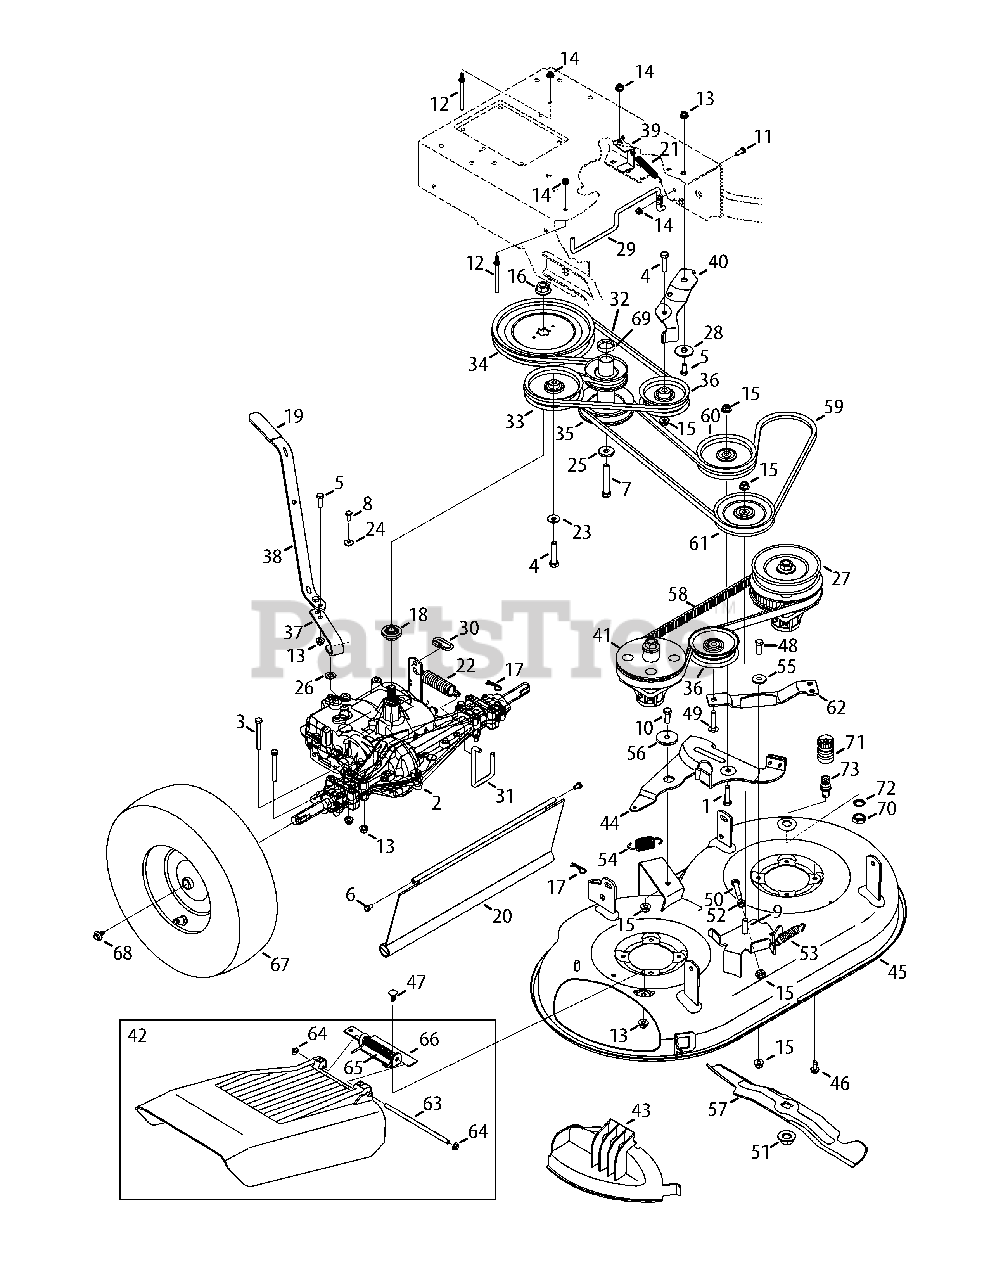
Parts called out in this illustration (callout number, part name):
1	Hex Head Cap Screw, 3/8-16 x 1.75
2	4 Speed Drive Assembly, Tecumseh
3	Hex Head Cap Screw, 5/16-18 x 2.75
4	Hex Head Cap Screw, 3/8-16 x 1.75
5	Hex Head Cap Screw, 5/16-18 x 1.00
6	Screw, 10-16 x 0.625
7	HHCS, 7/16-20 x 2.75
8	Hex Head Cap Screw, 1/4-28 x .625
9	Hex Head Cap Screw, 3/8-16 x 1.50
10	Hex Head Cap Screw, 3/8-16 x 1.25
11	Hex Head Cap Screw, 1/4-20 x .75
12	Belt Keeper, .25 DIA X 3.0
13	Flangelock Nut, 5/16-18
14	Flangelock Nut, 1/4-20
15	Flangelock Nut, 3/8-16
16	Flange Nut, 9/16-18
17	Click Pin, .092 x 1.64 LG
18	Spline Pulley Hub, 5/8
20	Trailshield, 8.35 x 19.17
21	Extension Spring, Wheel Drive
22	Extension Spring, Brake
23	Washer, Spring, .401 x .870 x .063
24	Washer, Bell, .265 x .75 x .062
25	Washer, Flat, .450 x 1.250 x .164
26	Washer, Flat, .39 x .87 x .06
27	Drive Spindle Assembly
28	Spacer, Shoulder, .5000 x .1475
29	Belt Keeper Rod
30	Coupling Link, 3/16
31	Brake Spring Mounting Rod
32	V Belt. 4L 64.2
33	Idler Pulley, 4.25 DIA
34	Flat Sheave, DIA 7.75
35	Engine Pulley, 3.20 x 4.35 DIA
36	Idler Pulley, 3.50 DIA
37	Lower Shaft Lever
38	Upper Shaft Lever
41	Spacer Spindle Assembly
42	Chute Deflector Assembly
43	Mulch Cover
44	Idler Arm Assembly
45	Deck Assembly
46	Screw, 5/16-18 x .750
47	Bolt, Carriage, 5/16-18 x .750
48	Hex Head Cap Screw, 3/8-16 x 1.00
49	Screw, Carriage, 3/8-16 x 1.75
50	Hex Head Cap Screw, 3/8-16 x 2.00
51	Flange Nut, 5/8-18
52	Hex Nut, 3/8-16
53	Extension Spring, Timing Belt
54	Extension Spring, Deck Brake
55	Shoulder Spacer, .625 ID x .169
56	Shoulder Spacer, .8840 x .190
57	2 in 1 Blade
58	Timing Belt, .315 x .787
59	Aramid V Belt, 72.2
60	Idler Pulley, 4.25" DIA
61	Idler Pulley, V-Type, 5.0 DIA
62	Timing Idler Bracket
63	Deflector Pin
64	Push Cap
65	Deflector Torsion Spring
66	Deflector Hinge Bracket
67	Wheel, 16 x 4 x 8
68	Screw, 5/16-24 x .750
69	Spacer, 1.0 x 1.28 x .31 (420CC)
70	Nut, Hex, M16-1.5
71	Water Nozzle Adaptor
72	Washer, Lock, 5/8
73	Deck Water Nozzle
